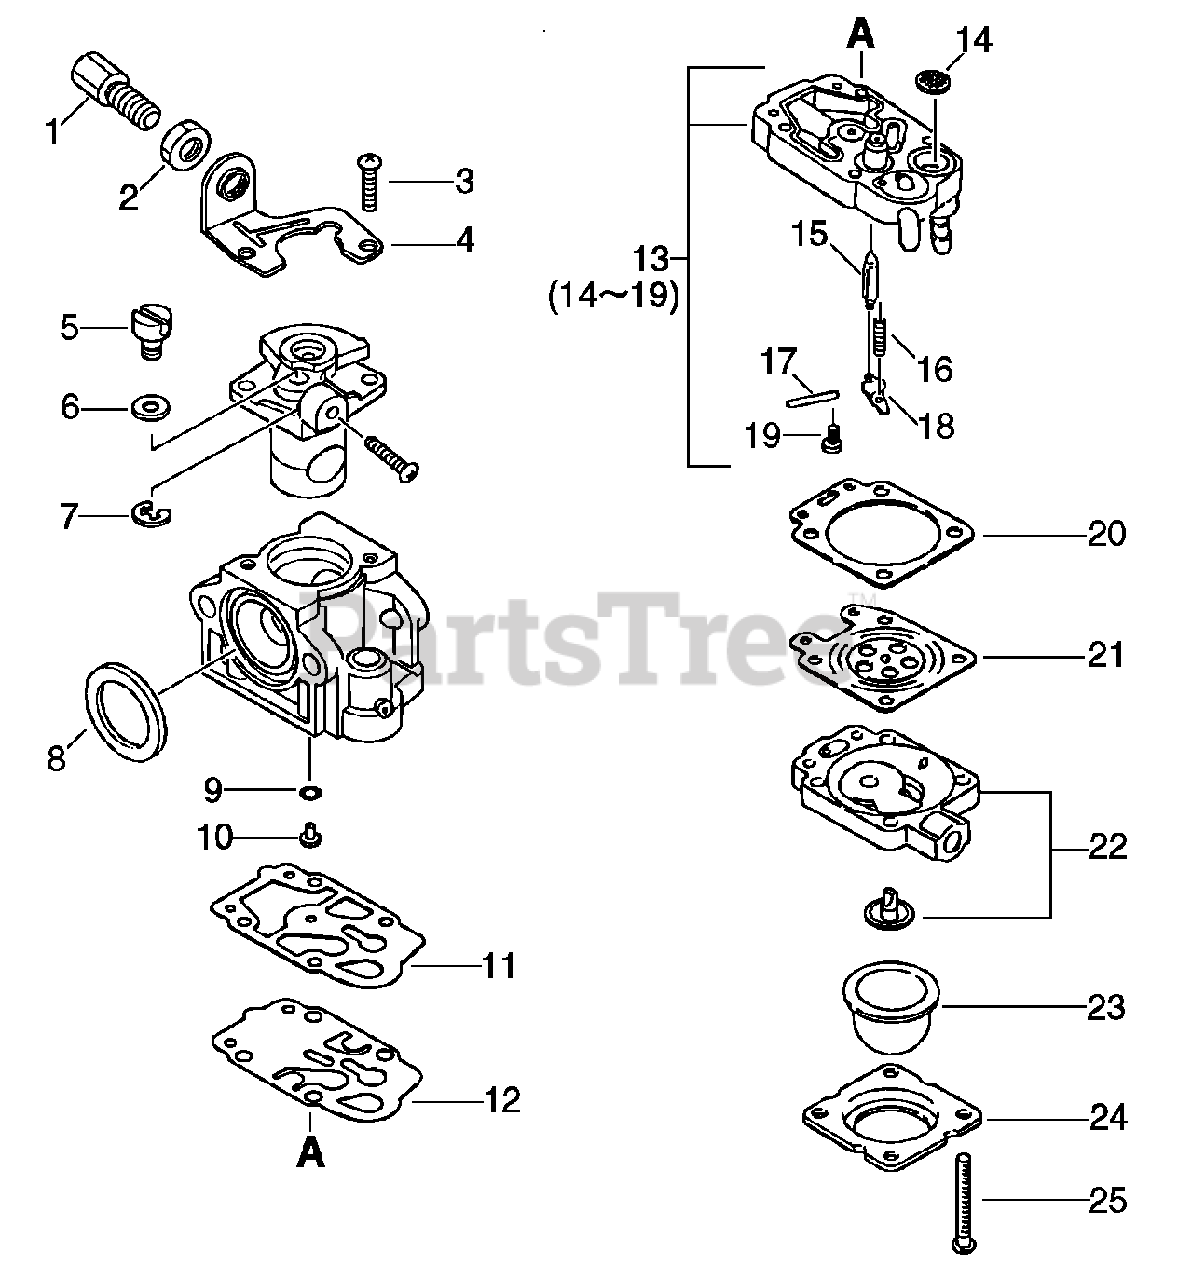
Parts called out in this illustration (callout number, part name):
1	ADJUSTER, THROTTLE CABLE
2	NUT, ADJUSTER LOCK M7
4	BRACKET, THROTTLE CABLE
8	RING, PACKING
10	JET, MAIN #37
11	GASKET, PUMP
12	DIAPHRAGM, FUEL PUMP
13	BODY ASSY, PUMP
14	SCREEN, FUEL INLET
15	VALVE, INLET NEEDLE
16	SPRING, METERING LEVER
17	PIN, METERING LEVER
18	LEVER, METERING
20	GASKET, METERING DIAPHRAGM
21	DIAPHRAGM, METERING
22	BODY ASSY, PURGE
23	BULB, PURGE
24	RETAINER, PURGE BULB
